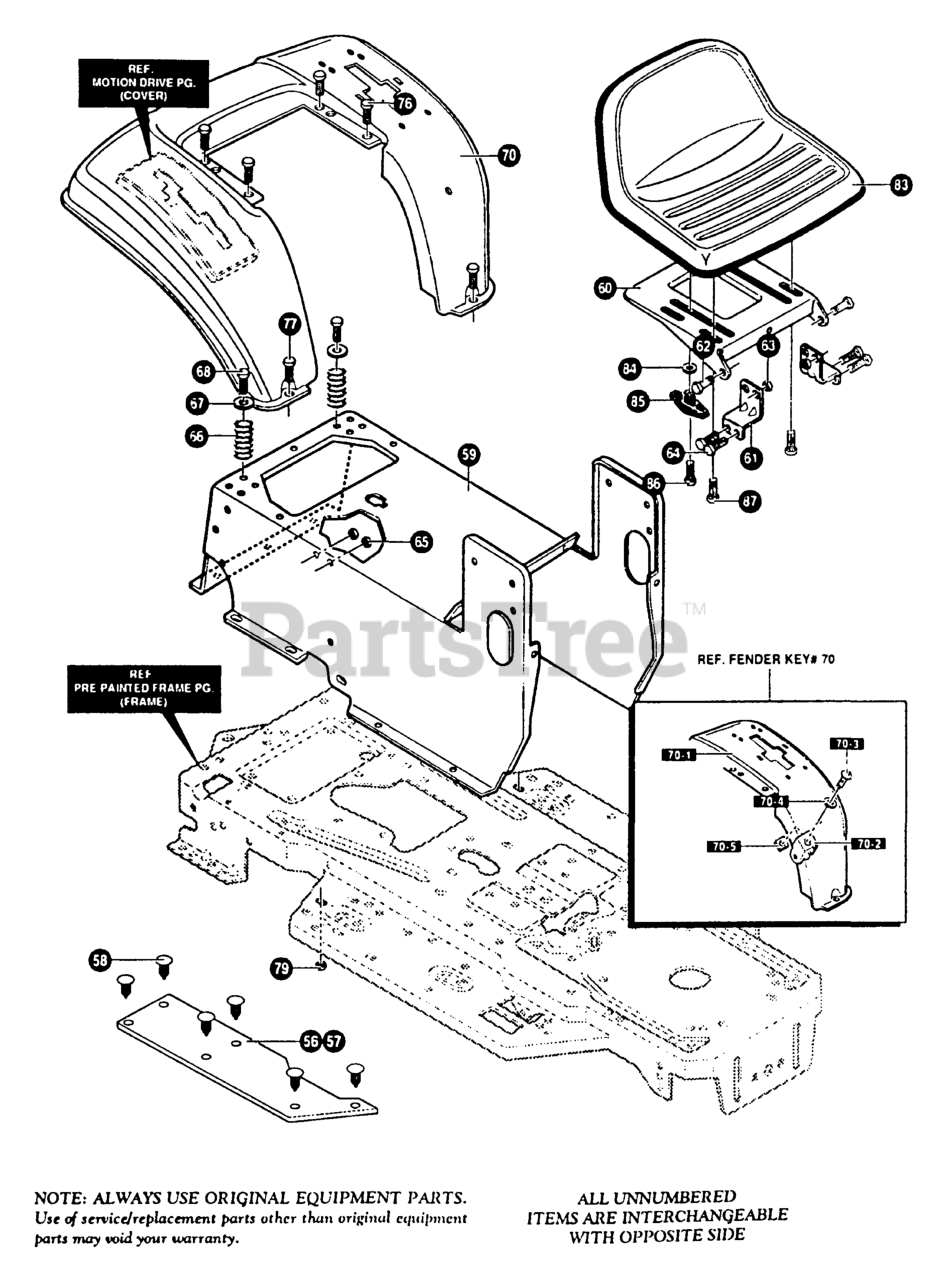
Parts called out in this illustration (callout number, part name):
56	FOOT PAD, LH
57	FOOT PAD, RH
58	FASTENER, RATCHET BLACK
60	PLATE, SEAT
61	BRACKET, SEAT SUPPORT
62	BOLT, .437 X .156
63	NUT, 5/16-18
64	SCREW, 5/16-18 x 0.63
65	NET, 5/16-18
66	SPRING, SEAT
67	WASHER, FLAT .281 X .63 X .065
68	SCREW, 1/4-20 X .50
70	ASSEMBLY, FENDER
70-2	CLEVIS
70-3	SCREW, 5/16-18 x 0.56
70-4	WASHER, .344 ID X 1.50 D X .09
70-5	NUT, 5/16-18 SQ
76	SCREW, 1/4-20 X .50
77	BOLT, 5/16-18 X 1.00
79	NUT, 5/16-18
84	WASHER, FLAT .344 X .69 X .065
85	HANDLE, WING NET
86	SCREW, 5/16-18 x 1.00
87	BOLT, .500 X .10
